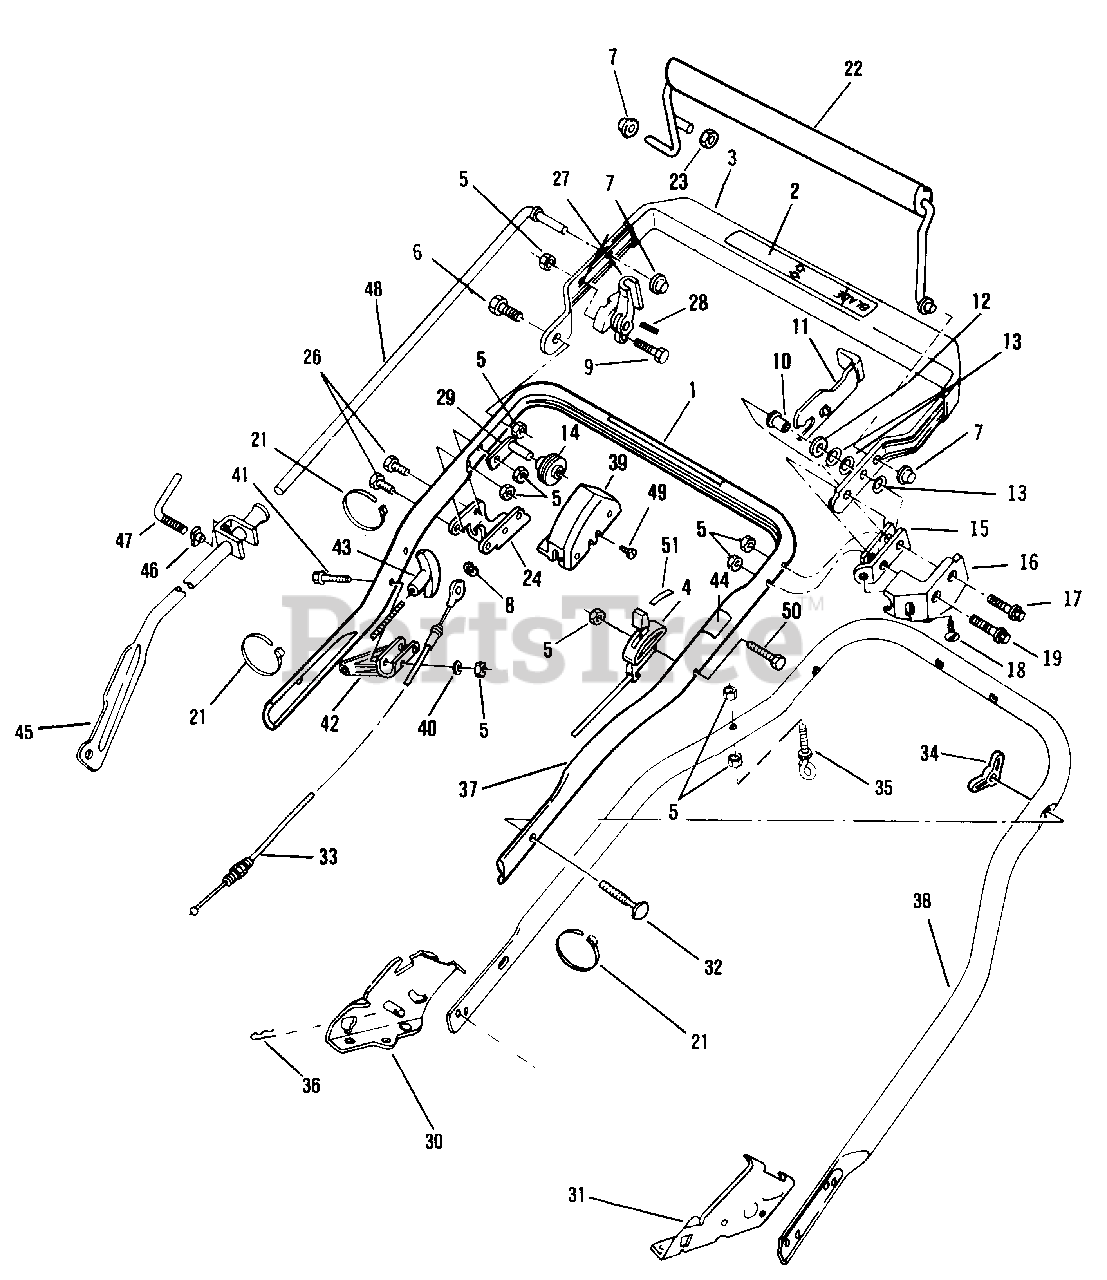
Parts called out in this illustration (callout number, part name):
1	Decal-Starting Instructions
2	Decal-Engine/Blade Control
3	Top Handle and Doubler Assembly
4	Control Assembly-Throttle
5	Locknut
6	Bolt-Shoulder-R.H.
7	Pushnut
8	Retaining Ring-Cable
9	Hex-Washer Head Shoulder Bolt
10	Spacer-Flanged
11	Lever-Lockout
12	Washer-Plain
13	Washer-Spring
14	Pulley
15	Down Stop
16	Guard-Lockout
17	Bolt-Shoulder
18	Screw
19	Bolt-Shoulder-L.H.
21	Tie Strap
22	Control Lever and Nut Assembly
23	Nut-Acorn
24	Bracket-Clutch Cable
26	Screw-Clutch Cable Bracket
27	Cam and Roll Pin Assembly
28	Roll Pin
29	Pivot-Bracket-Pulley
30	Handle Bracket-R.H.
31	Handle Bracket-L.H.
32	Screw
33	Control Cable Assembly
34	Knob
35	Eyebolt
36	Hair Pin-Handle Bracket
37	Handle Section-Center
38	Handle Section-Bottom
39	Cover
40	Washer-Plain
41	Screw-Truss Head
42	Rope Guide Assembly
43	Handle-Starter
44	Decal-Drive Lockout
45	Control Lever Assembly
46	Nut-Control Lever Clamp
47	Lever-Rod Clamp
48	Rod-Control
49	Screw-Hex Head
50	Screw
51	Decal-Throttle Control
